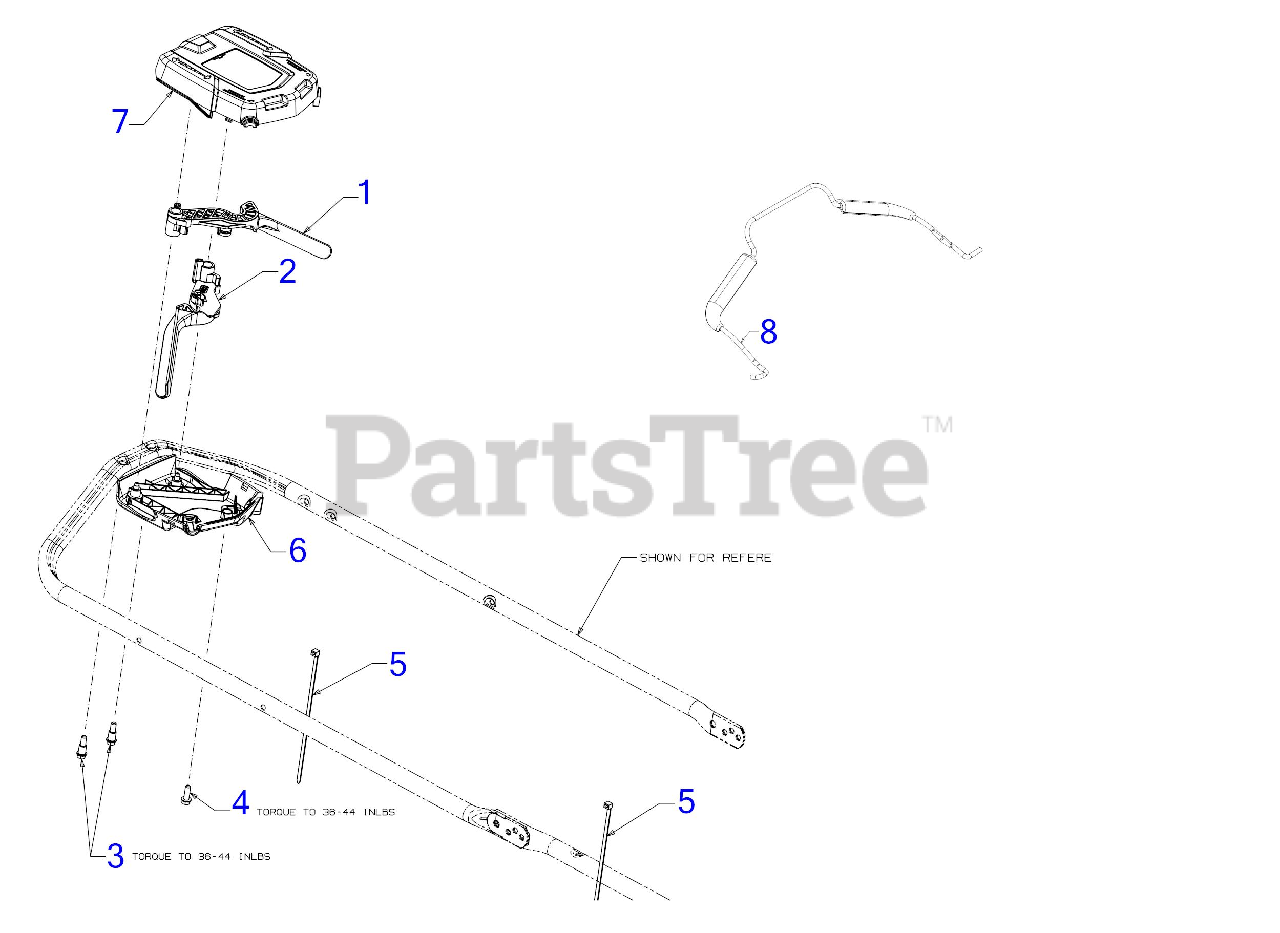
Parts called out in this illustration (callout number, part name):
1	CONTROL LEVER LH
2	CONTROL LEVER RH
3	SHOULDER SCREW 1/4-15 x .970
4	SCREW 1/4-15 x .750
5	7" CABLE TIE
6	LOWER CONROL HOUSING
7	UPPER CONTROL HOUSING
8	CONTROL BAIL
